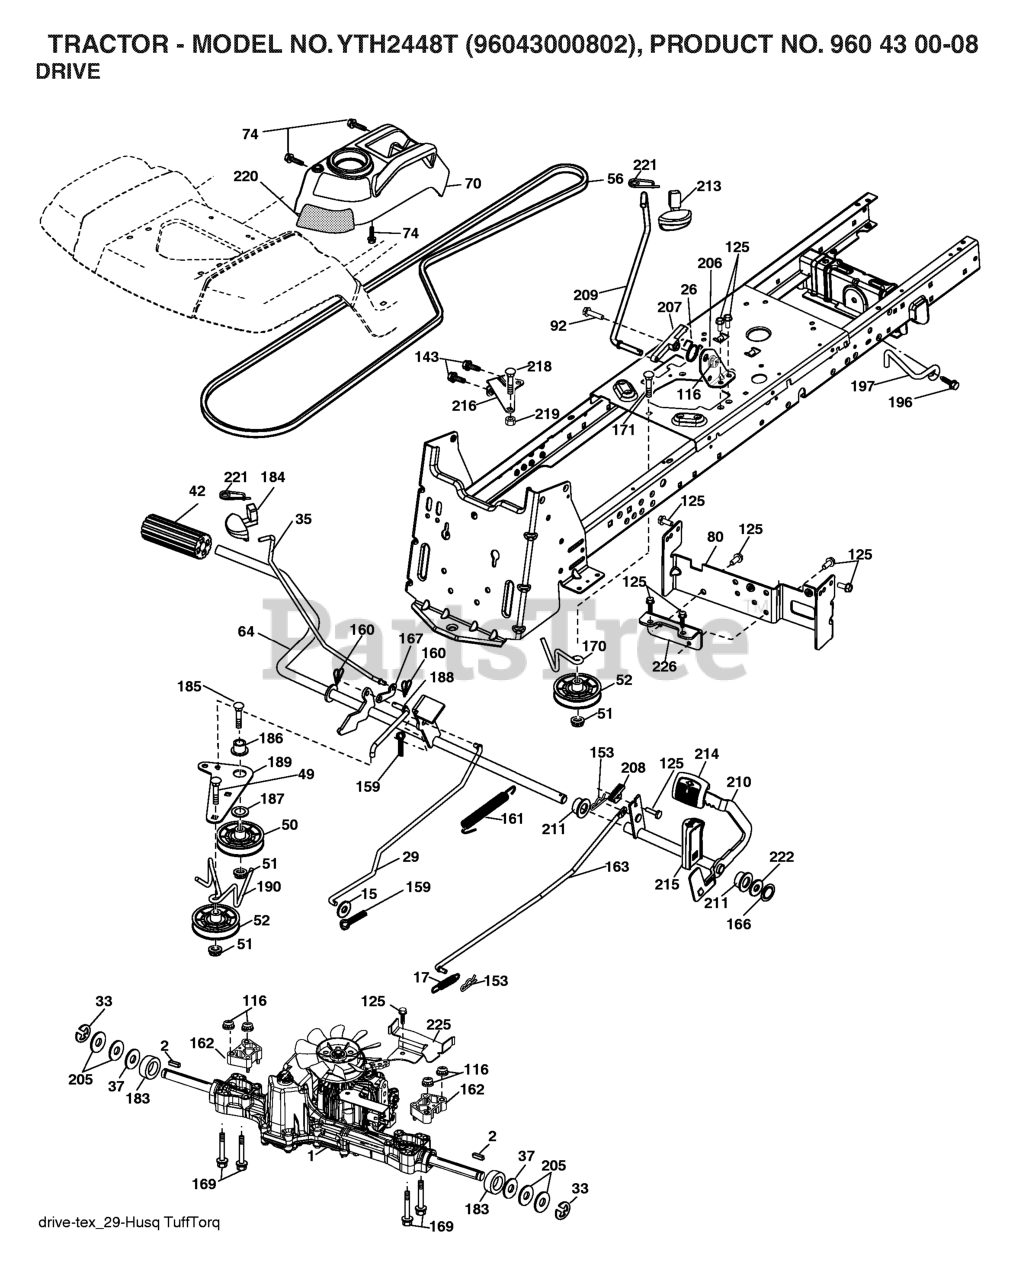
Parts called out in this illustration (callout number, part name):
1	TRANSAXLE.K46BN.PEDAL CONTROL
2	SQUARE KEY
7	HUB.ASM.WHEEL.REAR.22"
15	WASHER
17	SPRING.BRAKE.K46
26	SPRING.RETURN.CRUISE
29	ROD.BRAKE.K46
35	ROD.BRAKE.PARKING.GT.H
42	PEDAL COVER T
50	IDLER.FLAT.910.OFFSET
51	NUT LOCK FLG 3/8-16 UNC
52	IDLER.V-GROOVE.910.OFFSET
56	V-BELT.MOWER.92.40.42/K46
64	SHAFT.ASM.PEDAL.BRK.CNTR
70	RP CONSOLE.ASM.PCH.W/TB
74	SCREW.HI-LO.CONSOLE
80	STRAP.TORQUE.HG3000/K46
92	BOLT
116	NUT LOCK HEX FLANGE 5/16-18
125	SCREW
143	Screw 5/16-18 x 1/2 Hex, Self Tapping 5/16-18 x 1/2
153	RETAINER M
159	COTTER PIN
160	RETAINER CLIP
161	SPRING.RETURN.CLUTCH.2006
162	SPACER.TRANSAXLE.18&22
163	ROD.CONTROL.PEDAL.K46
166	NUT.PUSH.625.2006
167	LATCH.BRAKE.SPRING
169	BOLT.HEX.FLNG.5/16-18X3.75
170	KEEPER.V-IDLER.CENTER.
183	SPACER AXLE
184	HANDLE.PARKG.BRK.HUSQ X667
186	SPACER.RETAINER
187	WASHER 12/32X2X10GA
188	RP.LINK.CLUTCH.GROUND.DRIVE
189	BELLCRANK.GROUND.DRIVE.TEX.
190	KEEPER.BELLCRANK.DRIVE
196	SCREW 3/8-16X1
197	LINK.CLUTCH.ANIT-ROTAT
206	BRKT.MOUNT.LATCH.CRUIS
207	LATCH.CONTROL.CRUISE
208	GEAR.SECTOR.CONTROL.CR
209	ROD.CONTROL.CRUISE.GT.
210	ROCKER.ASM.PEDAL.CONTR
211	BEARING.NYLON
213	KNOB.CONTROL.CRUSIE.HU
214	PEDAL.FORWARD.TEX.GT.4
215	PEDAL.REVERSE.TEX.GT.4
216	BRACKET.PULLEY.IDLER.W/TEX
218	BOLT.5/16-18X1-1/4 FULL.THREAD
219	SPACER.FENDER
220	REFLECTOR.RH.TEX GT
221	RETAINER.SPRING.CLIP.H
222	WASHER
225	KEEPER.BELT.TRANSAXLE.K46
226	BRKT.MOUNT.TORQUE.K46.
